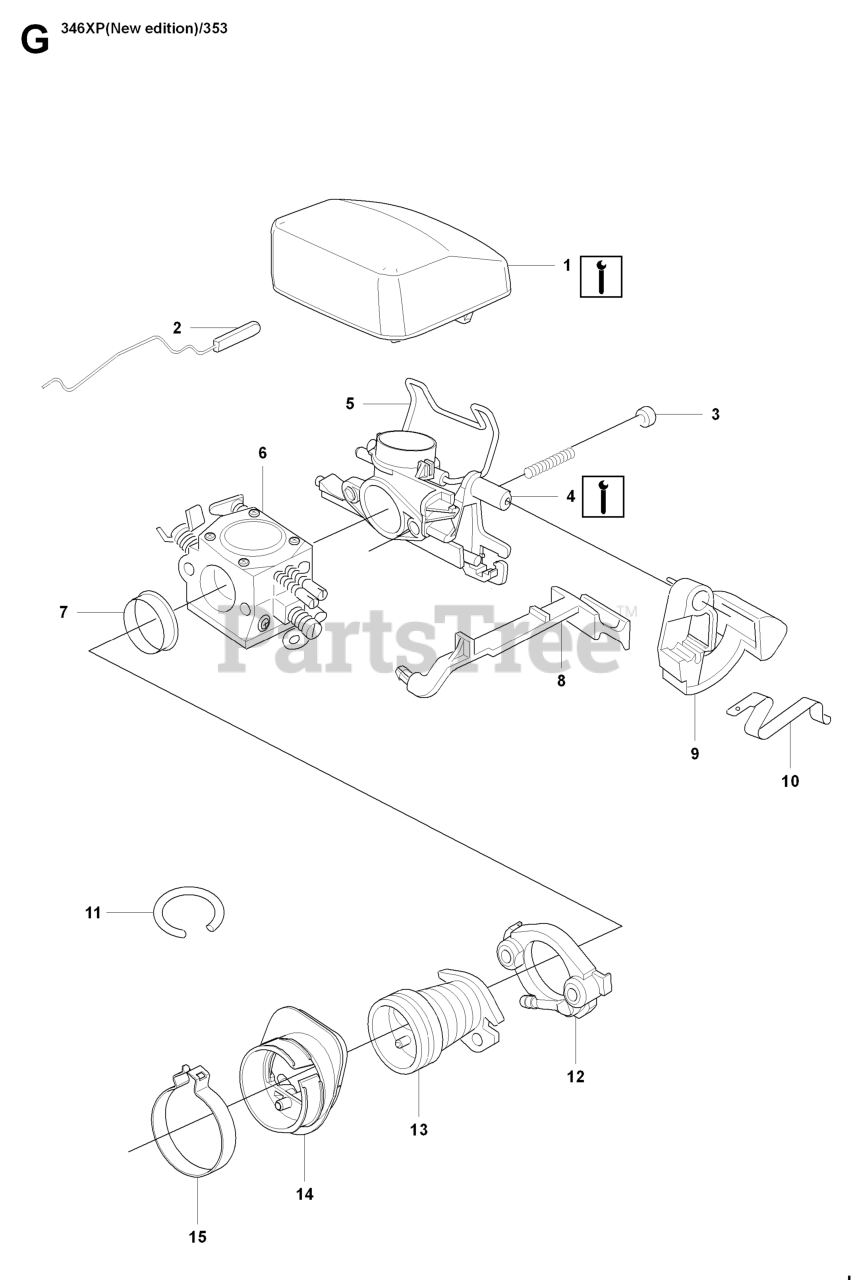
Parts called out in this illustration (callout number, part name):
1	AIR FILTER - NYLON (B)
1	AIR FILTER - FELT
1	AIR FILTER - NYLON (Y)
2	THROTTLE ROD
4	INLET ELBOW
5	FILTER CLAMP
6	CARBURETOR
8	CHOKE CONTROL
11	HOSE, IMPULSE
15	CLAMP, INTAKE
